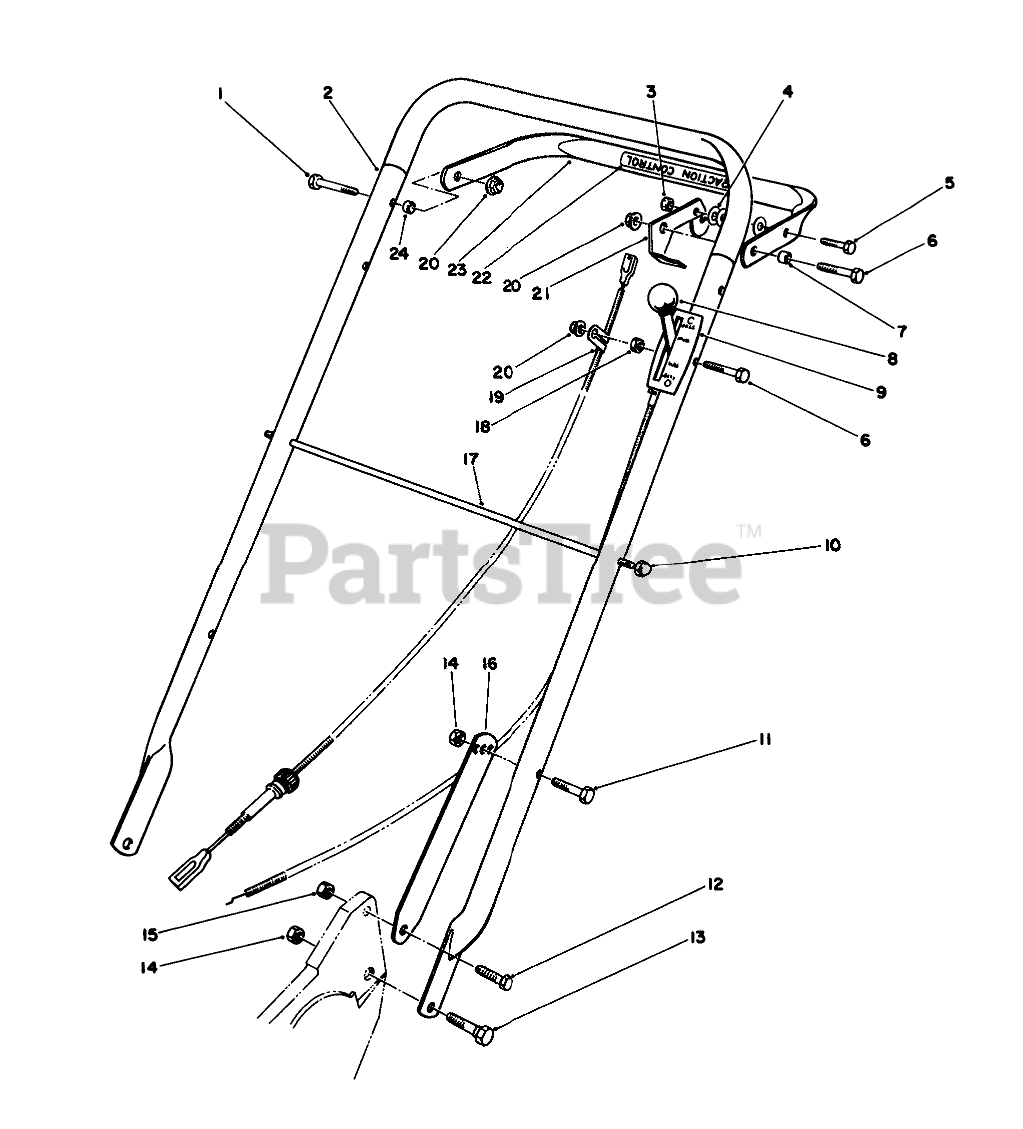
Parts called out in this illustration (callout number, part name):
1	SCREW-HH
2	Handle
3	NUT-LOCK, NI
4	WASHER-FLAT
5	SCREW-HH
6	SCREW-HH
7	Standoff-Lift Bail
8	KNOB-CONTROL
9	Control-Throttle (Incl. Ref. #8) Bend Type # 1 Sheath Lg.-46.5 Inch Wire Lg.-2.5 Inch
10	NUT-CAP
11	SCREW-HH
12	SCREW-HH
13	SCREW-SHOULDER
14	NUT-LOCK, CONE
15	NUT-LOCK, NI
16	Latch-Handle
17	ROD-SUPPORT, BAG
18	NUT-JAM
19	TRACTION CABLE
20	NUT-LOCK, HHF
21	Lever-Control
22	TRACTION DECAL
23	Lift Bail
24	STANDOFF LIFT BAIL
